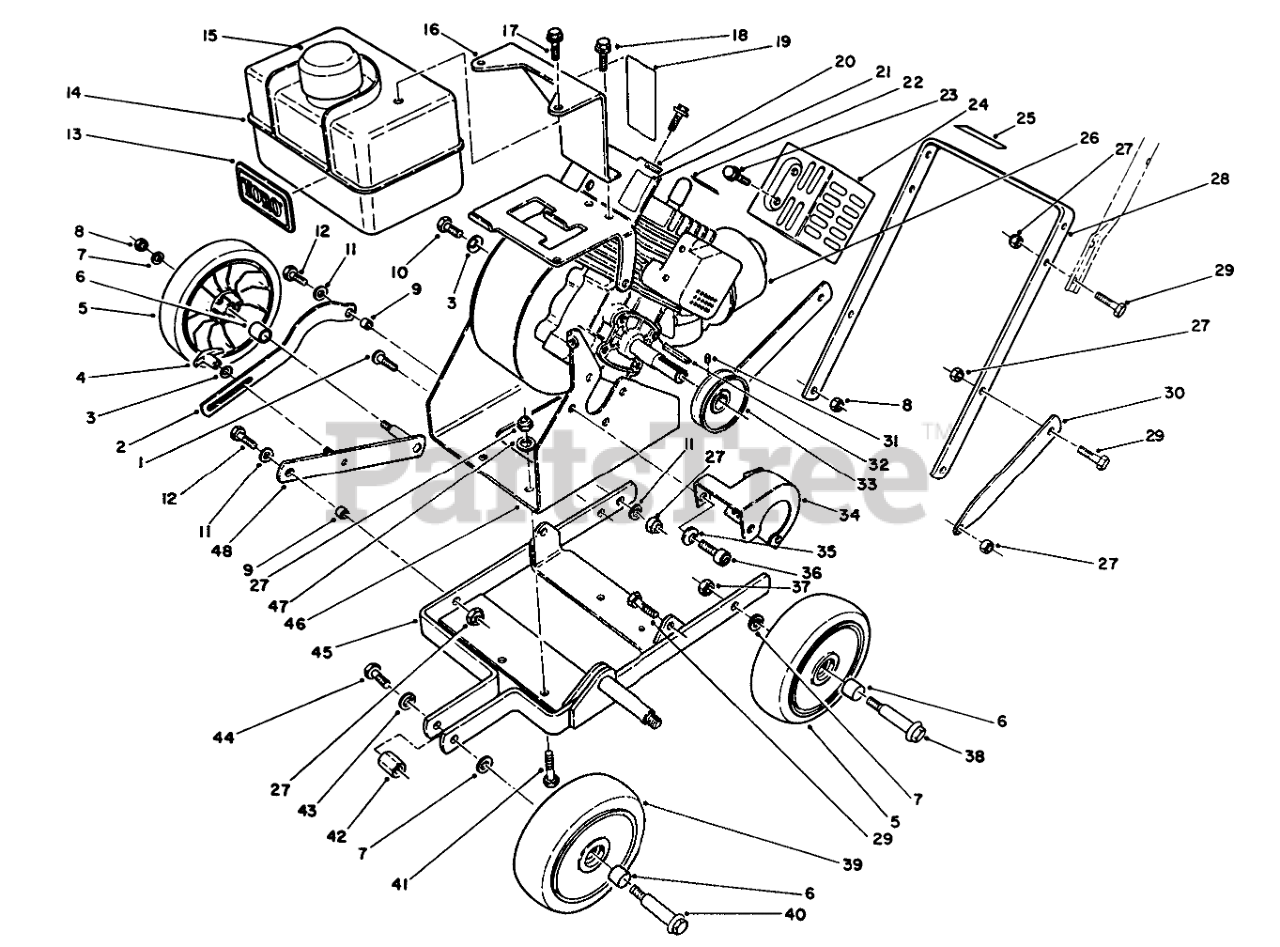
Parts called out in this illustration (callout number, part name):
1	3/8-24 X 1.00HEX BU. HD
2	AXLE LINK
3	BELLEVILLE SPRING WASHE
5	Wheel & Tire Assembly (Incl. Ref. #6)
6	BUSHING
7	WASHER
8	NUT-LOCK
9	WHEEL MT BUSHING
10	SCREW-HH
11	WASHER-FLAT
12	SCREW-HH
13	TORO LOGO PLT
15	Cap-Fuel
16	TANK STRAP
17	Screw-Cap Hex. Hd.
18	SCREW-HWHTF
19	Decal-Fuel Mixture
20	TANK BASE
21	DECAL-SURFACE, HOT
22	DECAL-IGNITION
23	Screw-Cap Hex. Hd.
24	MUFFLER COVER
25	DECAL-WARNING
26	Engine-2 Cycle
27	NUT-LOCK, NI
28	LOWER HANDLE
29	SCREW-HH
30	SUPPORT HANDLE
31	SCREW-SET
32	KEY-SQUARE
33	2HP PULLEY
34	GUARD-ENGINE PULLEY
35	WASHER-BELLEVILLE
36	SCREW-HSH
37	NUT-HEX
38	WHEEL BOLT
39	Wheel & Tire Assembly (Incl. Ref. #6)
40	BOLT-WHEEL
41	SCREW-HH
42	HEX SPACER
43	WASHER-LOCK
44	SCREW-HH
45	Frame-Edger
46	ENGINE FRAME
47	WASHER-PLAIN
48	WHEEL MOUNT WA
